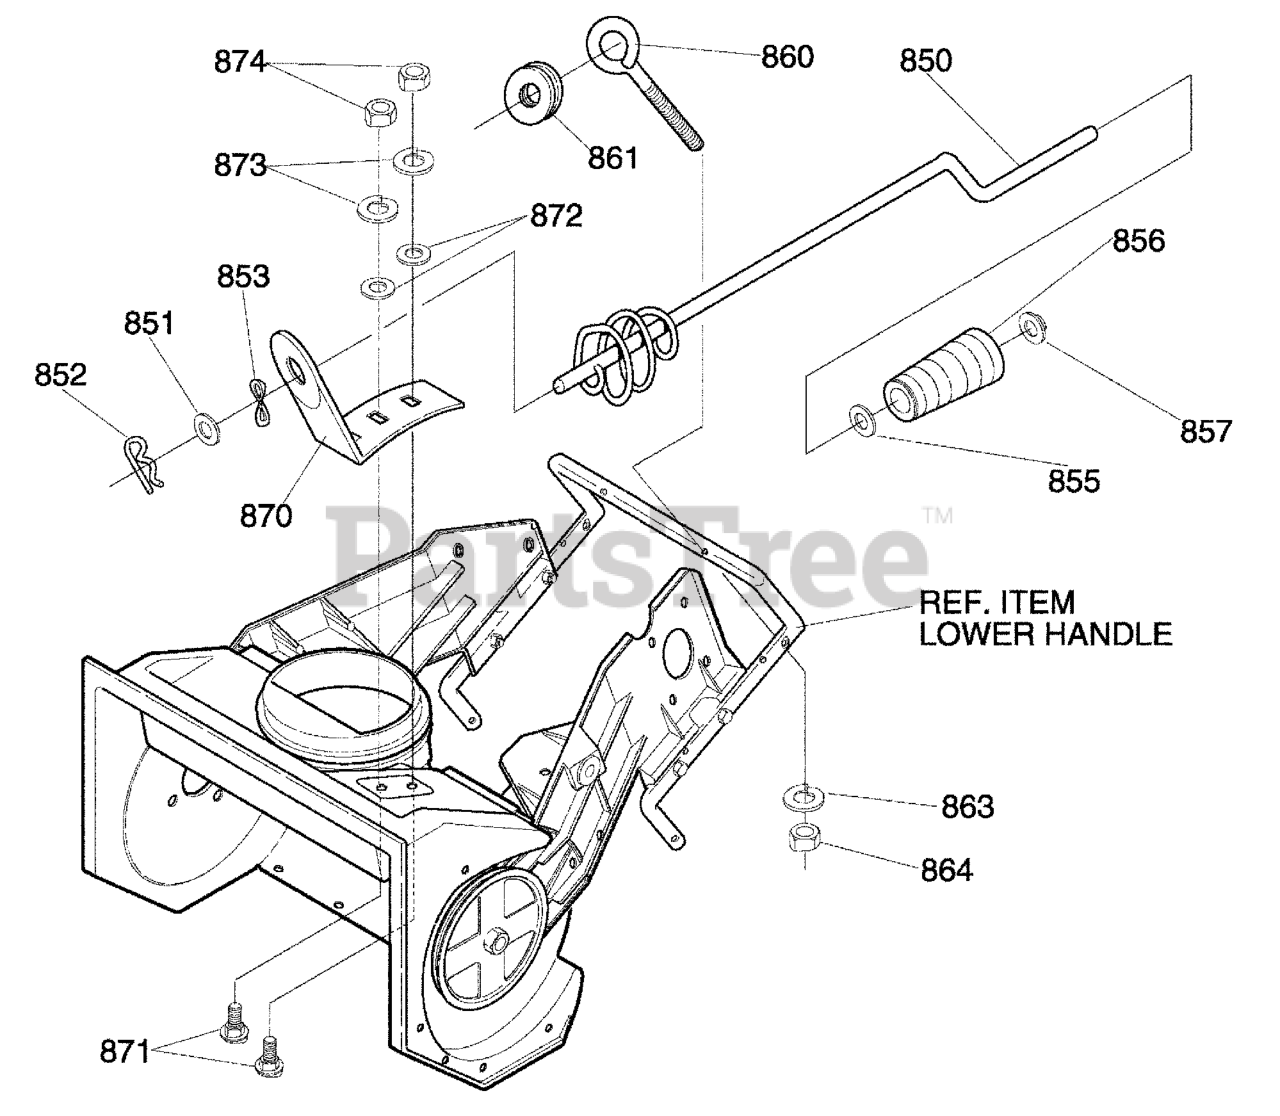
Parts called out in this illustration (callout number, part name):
850	ROD, ASSY UPPER CHUTE CONTROL
851	WASHER, FLAT .406X.81X.066
852	PIN, COTTER .094 DIAX1.00LG
853	WASHER, CURVED SPRING
855	WASHER, FLAT .406X.81X.066
856	KNOB, SLEEVE
857	NUT, PUSH
860	BOLT, EYE 3/8-16X2.00
861	GROMMET, EYE BOLT
863	WASHER, MDSPTLK
864	NUT, 3/8-16 HEXJAM
870	BRACKET, CHUTE ROTATE
871	BOLT, 5/16-18X.75 CARR.
872	WASHER, FLAT .349X.69X.066
873	WASHER, HVSPTLK .328 x .60 x .09
874	NUT, 5/16-18 REGHEX
